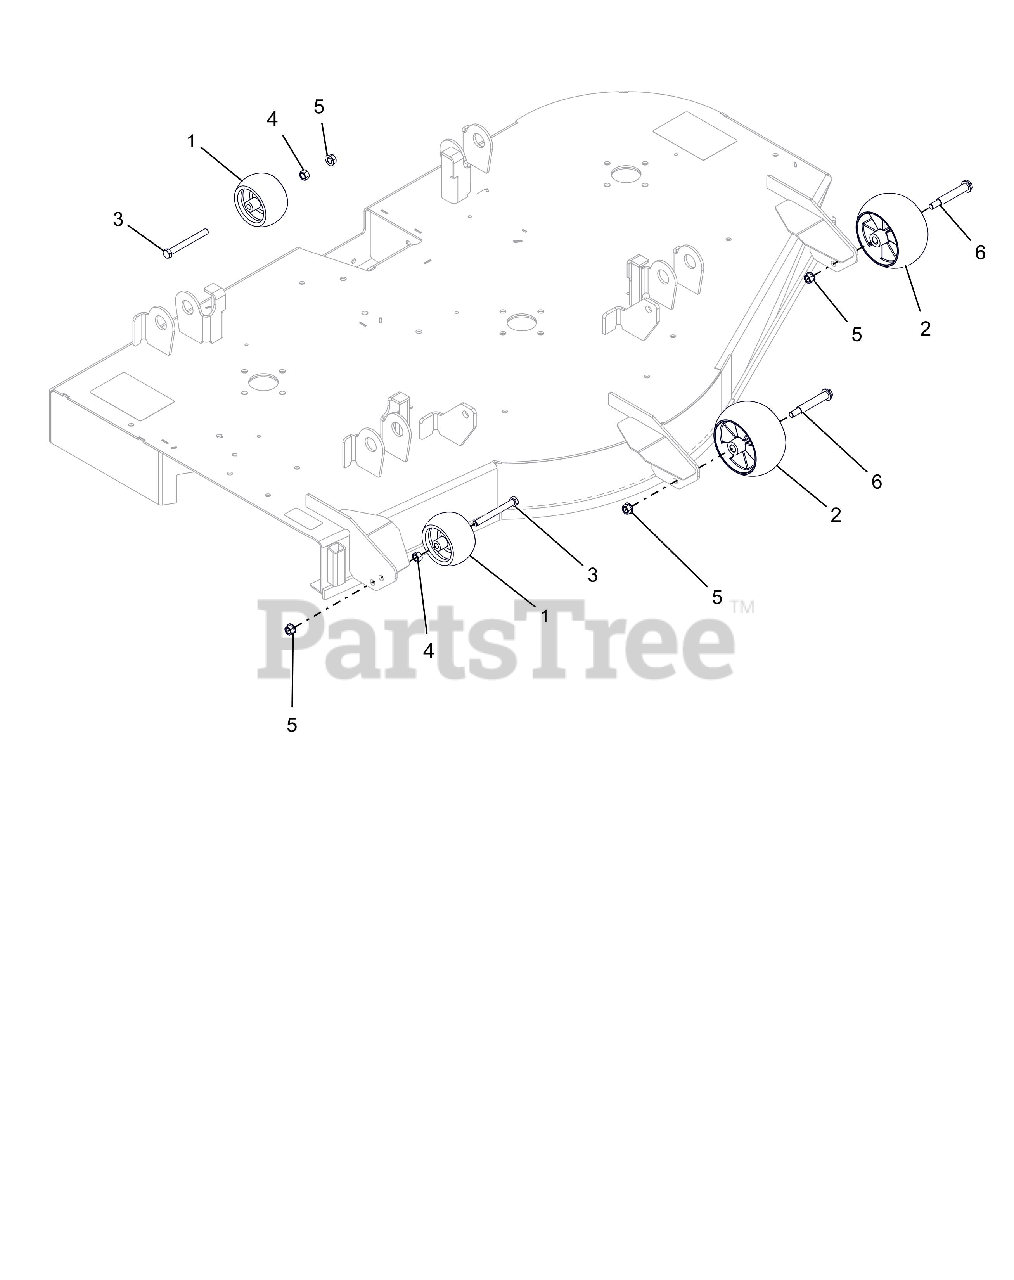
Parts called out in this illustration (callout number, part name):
2	ANTI-SCALP WHEEL - 5X OS
3	@BLT-HEX .38-16X3.50 GR5 YWZC
4	@NUT-HEX .38-16 YWZC
5	@NUT-LK-TOP-FLG .38-16 YWZC
6	BLT-SHLDR .38-16X2.50 HWH G5
